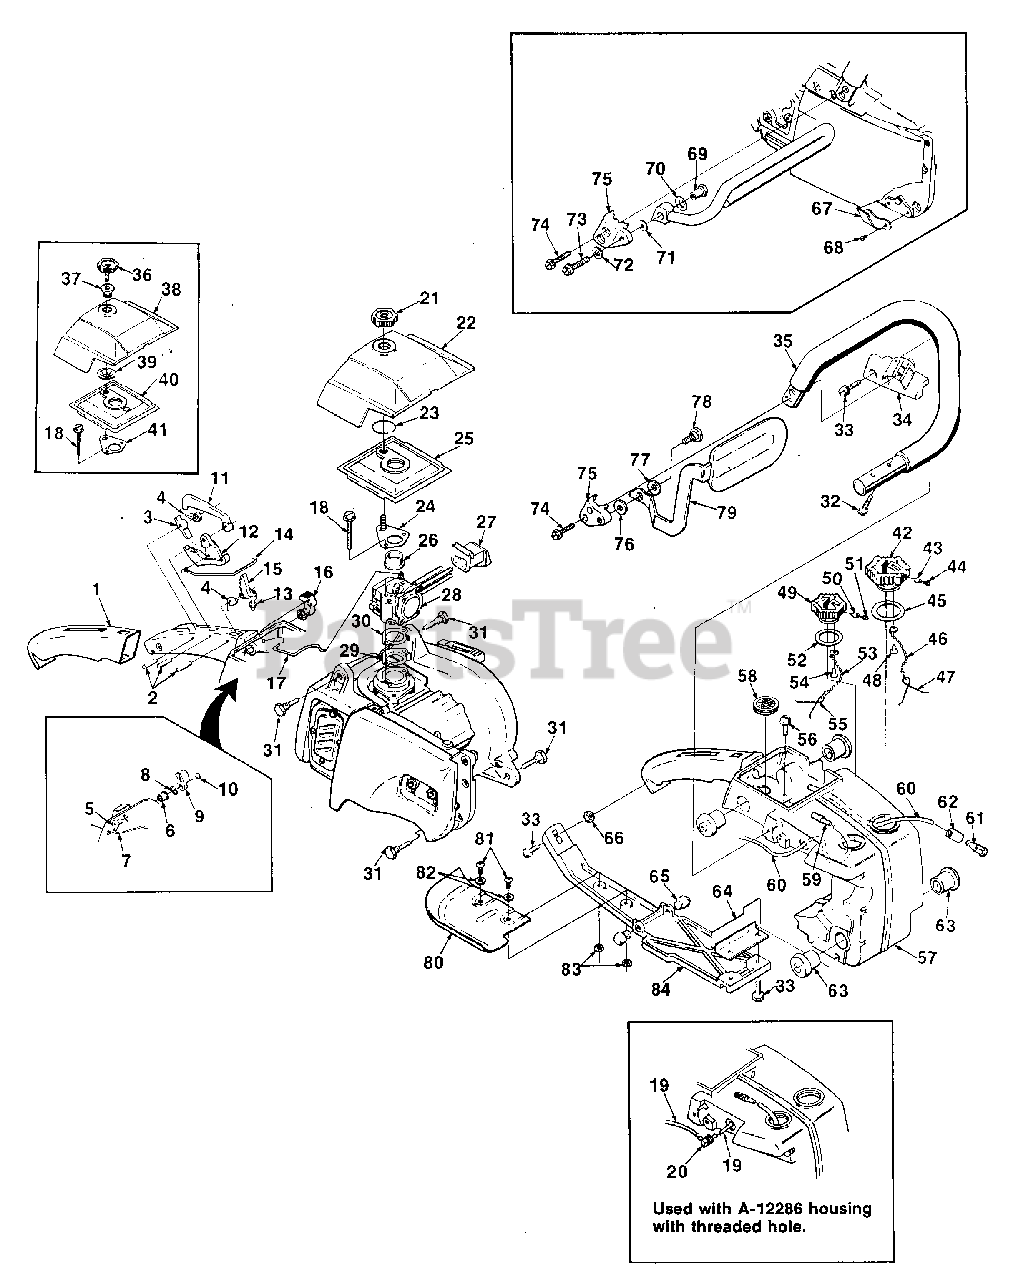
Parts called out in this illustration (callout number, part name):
1	GRIP- Throttle handle
2	PIN- Dowel
3	LEVER- Trigger lock
4	SPRING- Torsion
5	SHAFT- Choke (prior to lot # 1054)
6	BUSHING (prior to lot #1054)
7	ROD- Choke (prior to lot #1054)
8	WASHER- Wave (prior to lot #1054)
9	KNOB- Choke (prior to lot #1054)
10	SCREW- 8-32 x 1/2 (prior to lot #1054)
11	LOCK- Trigger
12	KIT- Trigger & Screw
13	SCREW- Trigger latch
14	ROD- Throttle
15	LATCH- Trigger
16	KNOB- Choke (After lot #1054)
17	ROD- Choke (After lot #1054)
18	SCREW- Hex sems 10-24 x 1.75
19	TUBING- Rubber (oil) 4 3/4"
20	FITTING- Oil line
21	NUT- Filter cover mtg.
22	COVER- Filter
23	RING- Retaining
24	BRACKET- Mounting cover
25	FILTER- Air
26	BUSHING- Flange
27	GROMMET- HI-LOW
28	CARBURETOR- (HDC-39-A)
31	PIN- Isolator
32	SCREW- Soc. hd. 10-24 x 7/8
33	SCREW- Hex sems 10-24 x 3/4
34	BRACKET- Handle bar
35	HANDLE BAR
36	NUT- Filter cover mounting
37	BUSHING- Nylon
38	COVER- Air filter
39	NUT- Push on spring
40	FILTER- Element air
41	PLATE- Spring
42	CAP- Fuel filler
43	VALVE- Check (oval duckbill)
44	FILTER- Filler cap
45	GASKET- Fuel cap
46	CHAIN- Bead
47	RETAINER
48	SCREW- Pan hd. plastite 6 x 1/4
49	CAP- Oil filler
50	VALVE- Check (oval duckbill)
51	FILTER- Filler cap
52	GASKET- Oil cap
53	CHAIN- Bead
54	SCREW- Pan hd. plastite 6 x 1/4
55	RETAINER- Cap
56	SCREW- Hex sems 10-24 x 5/16
57	HOUSING- Engine
58	SCREEN- Air inlet
59	FINDER- Oil
60	TUBING- Rubber (Fuel) 10 1/2"
61	PICK-UP- Fuel
62	FILTER- Felt
63	SET- Isolator- soft (set of four)
64	DEFLECTOR- Air (exhaust)
66	NUT- Hex 10-24
67	STOP- Chain
68	SCREW- Hex sems 8-32
69	SPACER- Nut (prior to lot #9240)
70	WASHER- Cupped spring (prior to lot #9240)
71	WASHER (prior to lot #9240)
72	WASHER (prior to lot #9240)
73	SCREW- Hex sems 10-24 x 1 1/4 (prior to lot #9240)
74	SCREW- Hex sems 10-24 x 1 3/8
75	BRACKET- Hand guard
77	WASHER- Belleville
78	SCREW- Shoulder
79	GUARD- Hand
80	KIT- Right hand guard
81	SCREW- Hex hd. cap
83	NUT- Center lock #10-24
84	BRACE- Handle
